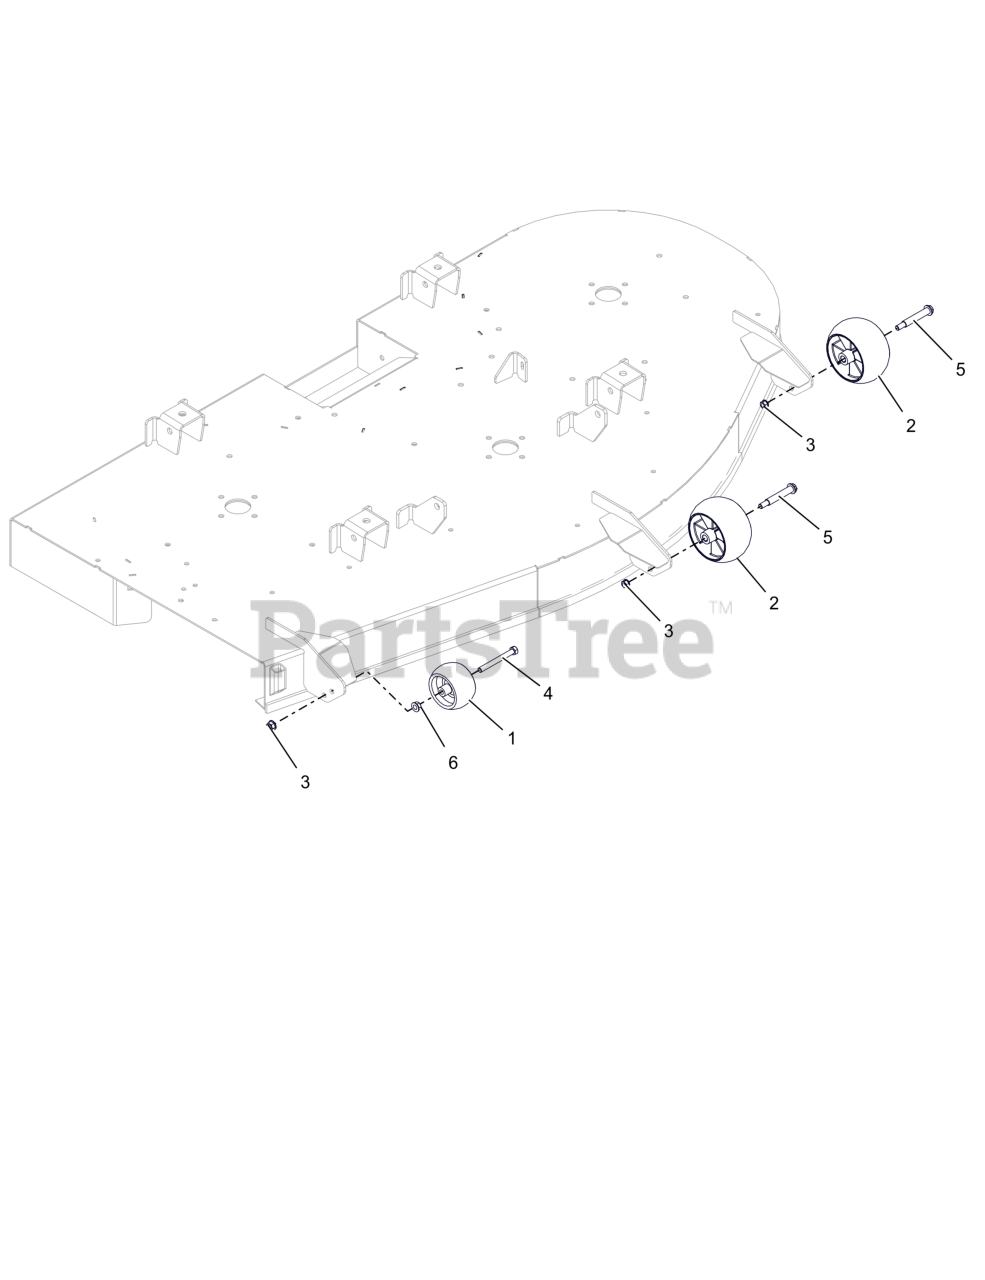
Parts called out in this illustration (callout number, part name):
2	ANTI-SCALP WHEEL - 5X OS
3	NUT, FLG-CTR LK .
4	BLT, HEX .38-16X3.50 G5 ZCC
5	BLT-SHLDR .38-16X2.50 HWH G5
6	NUT-LK-CTR-FLG .375-16 GF ZCC
